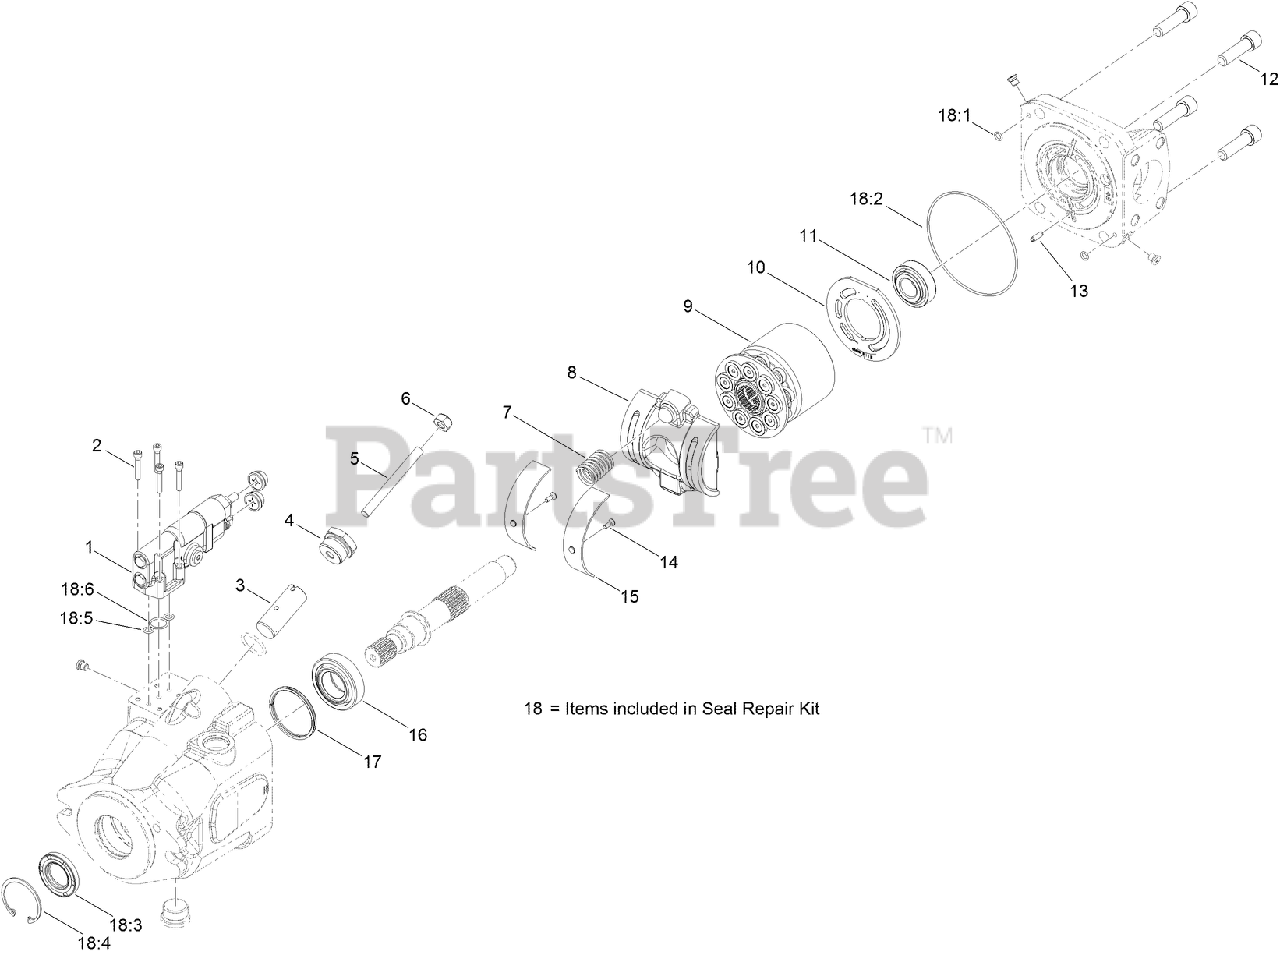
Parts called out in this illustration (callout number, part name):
1	COMPENSATOR ASM
2	SCREW-CAP
3	PISTON-CONTROL
4	PLUG-ADJUSTER, STROKE
5	SCREW-SET, ADJUSTER
6	NUT-SEALING
7	SPRING-BIAS
8	SWASHPLATE
9	ROTATING ASM
10	PLATE-VALVE
11	REAR SHAFT BEARING ASM
12	SCREW-CAP
13	PIN-ROLL
14	SCREW-HSFH
15	BEARING-SWASHPLATE
16	FRONT SHAFT BEARING ASM
17	RING-CRUSH
18	SEAL KIT
18:1	O-RING
18:2	O-RING
18:3	SEAL-SHAFT
18:4	RING
18:5	O-RING
18:6	O-RING
